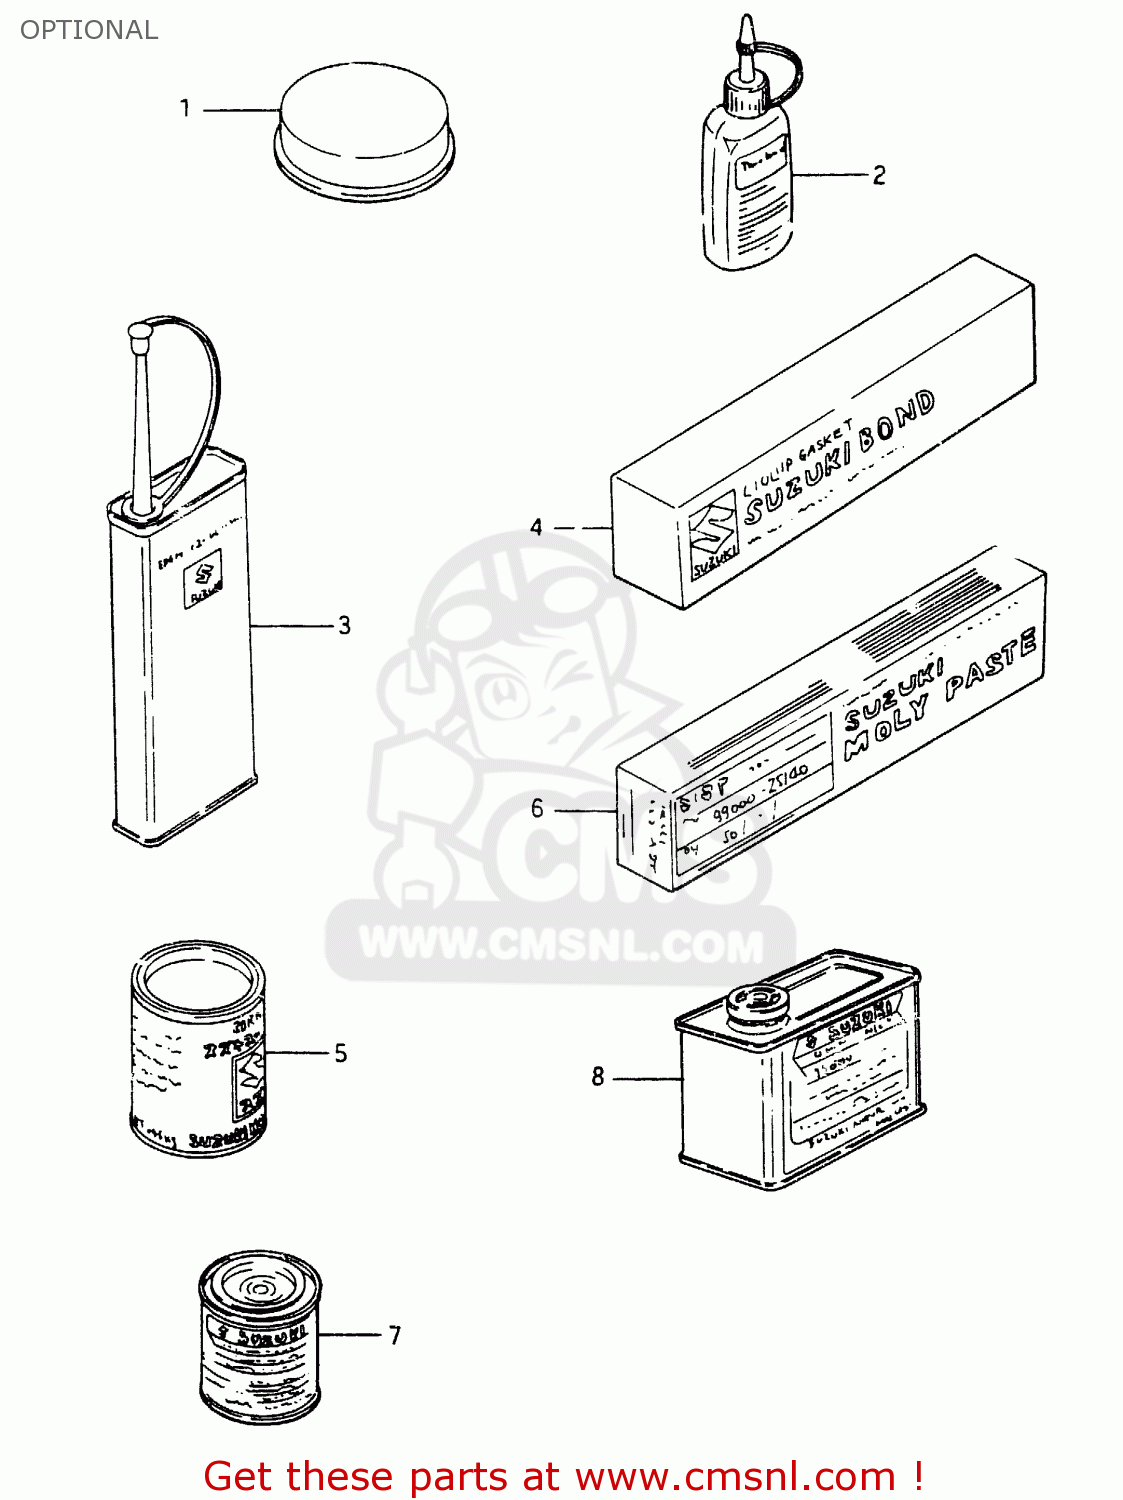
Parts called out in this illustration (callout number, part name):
1	GREASE,PBC FOR BRK PAD 20G
2	THREAD LOCK NO.1342
3	THREAD LOCK NO.1401 CLEAR 200G
4	LIQUID GSKT NO.1207B 100G BLK
5	GREASE(C)EP2 LITHIUM 150G
6	SUZUKI MOLY PASTE
7	PAINT,BLACK
8	PAINT (BLACK)
